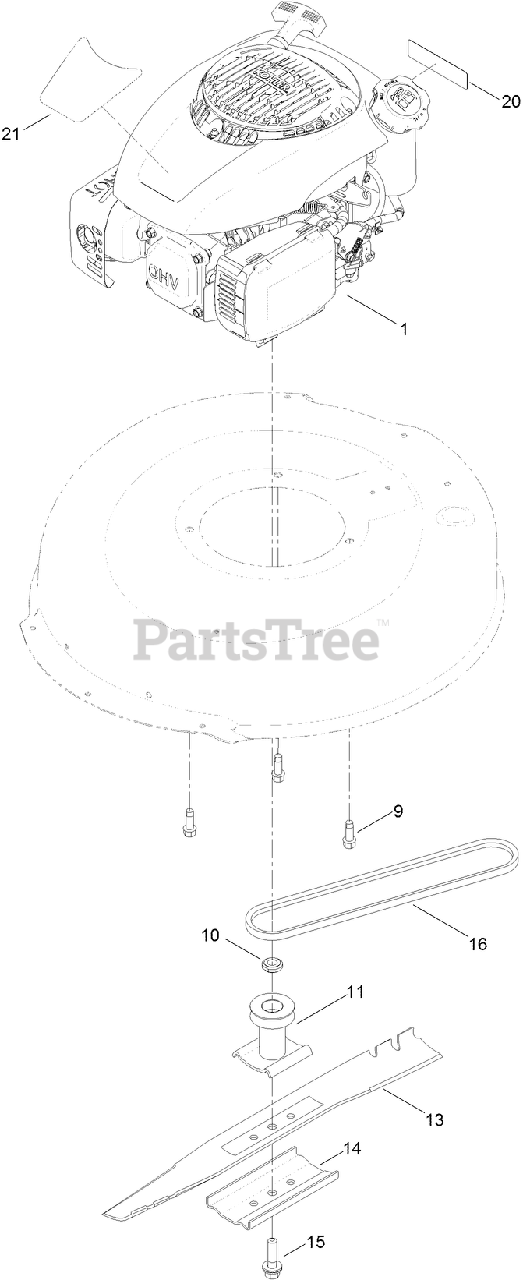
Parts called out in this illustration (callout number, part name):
9	SCREW-TAPTITE
10	SPACER-DRIVER
11	DRIVER-BLADE
14	SUPPORT-BLADE
15	BOLT-BLADE
20	DECAL-ARRESTER, SPARK
